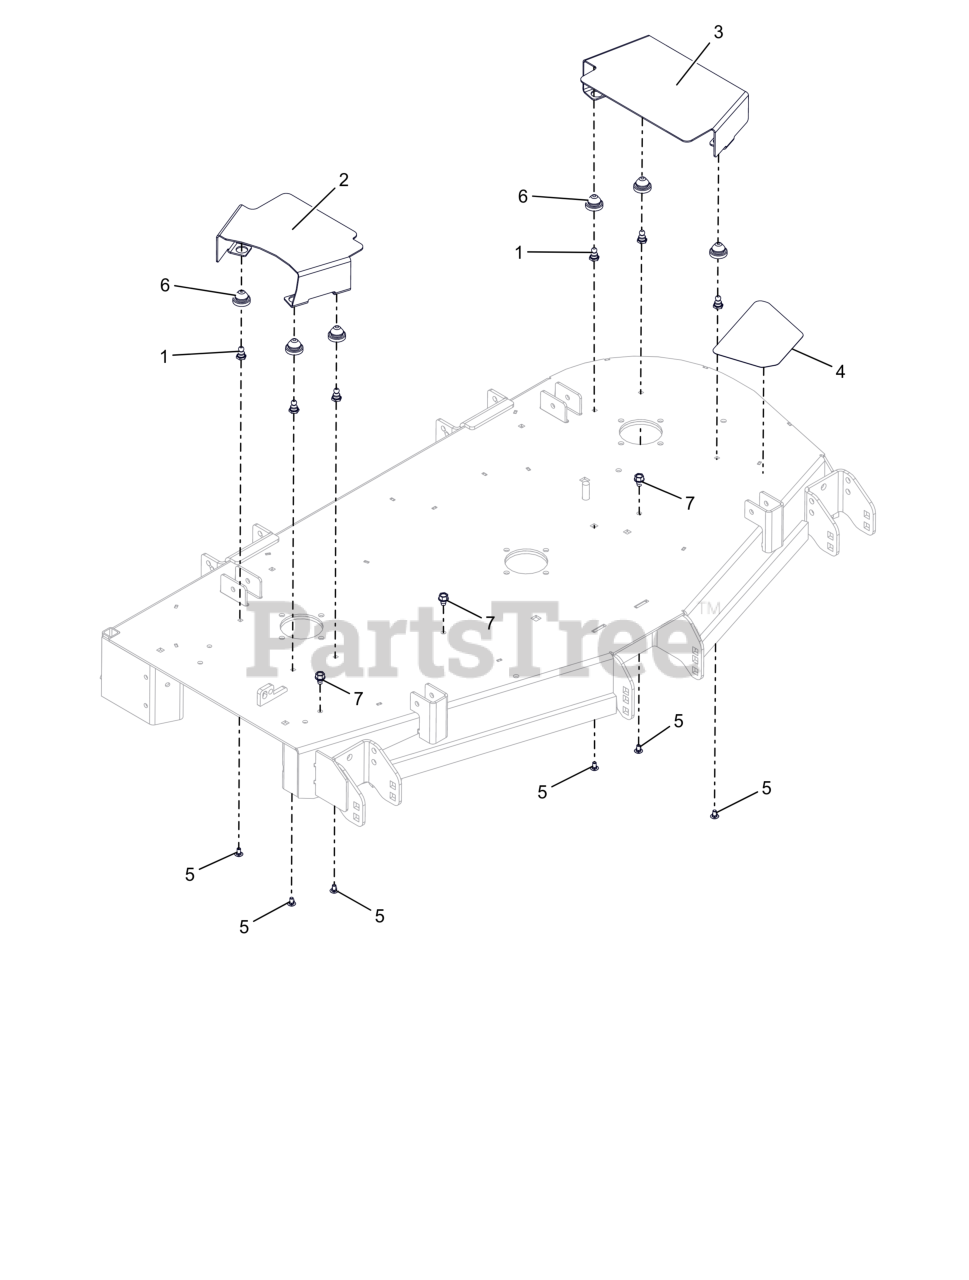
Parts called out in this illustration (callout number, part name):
1	STUD, BALL FEMALE .250-20 THREAD
2	GUARD, RH DECK BELT (RED)
3	GUARD, LH DECK BELT (RED)
4	GRIP, STEP ANTI SKID
5	BLT, RHSSN.25-20X.500 G5 ZCC
6	COUPLING, RUBBER PUSH-IN
7	SCR,TAP .375-16X.50 HWH TR ZCC
